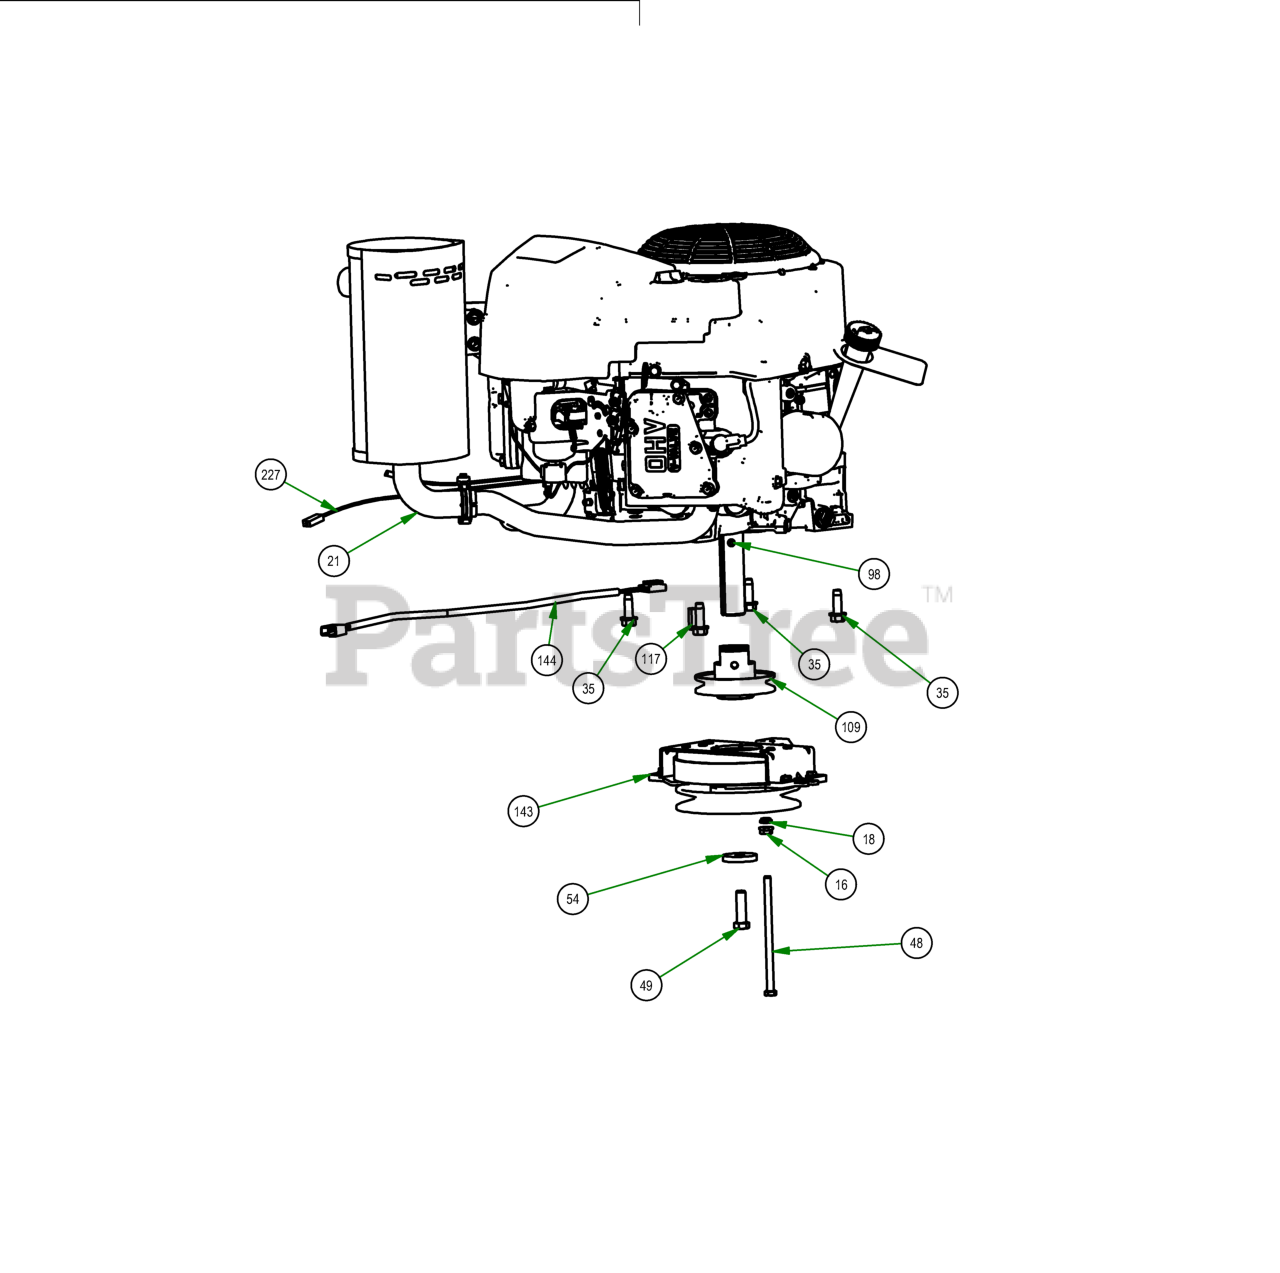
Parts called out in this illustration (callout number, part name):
16	5/16-18 HEX SERRATED FLANGE NUT HARD/ZINC
18	5/16-18 Nylock Insert Jam Locknut
21	Exhaust Assembly
35	3/8-16 X 1-1/8HEX WASHER UNSLOT SERRATED (TRI-LOB) TRS ZINC YELLOW
48	5/16-18 X 5-1/2 HEX CAP SCREW (GR.5) ZINC
49	7/16-20 X 1-1/2 HEX CAP SCREW (GR.8) w/ Patch
54	CLUTCH WASHER
98	5/16 Set Screw
109	3-3/4" Motor Pulley SD
117	1/4" x 1" Key
144	Clutch Pigtail
227	Harness Adaptor
